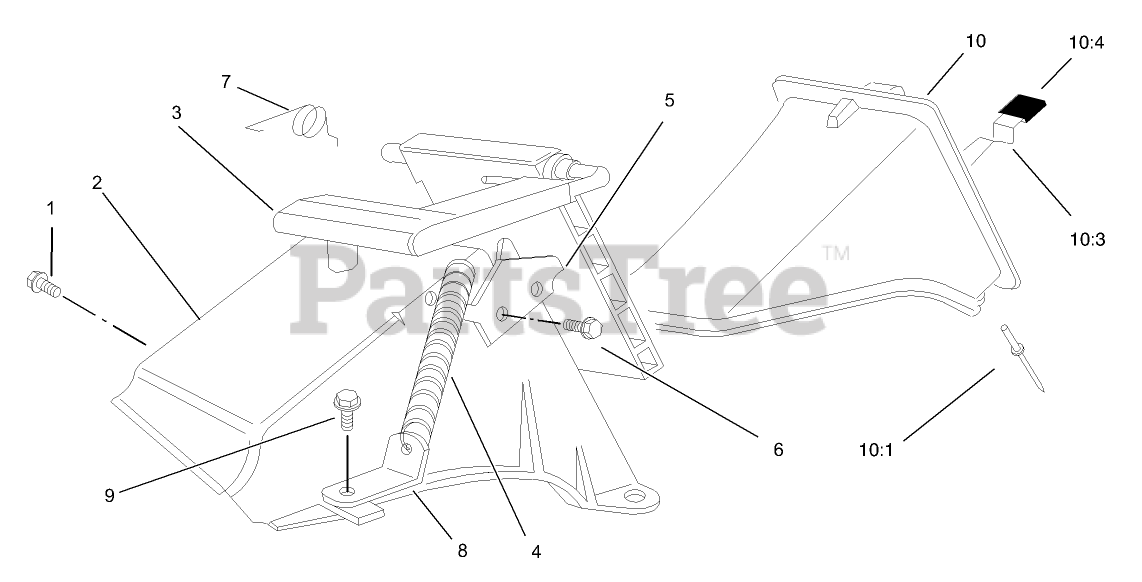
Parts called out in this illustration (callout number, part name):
1	SCREW AND WASHER ASM
2	TUNNEL-DISCHARGE
3	DISCHARGE DOOR ASM
4	SPRING-DOOR
5	PLATE-LATCH
6	SCREW-PLASTITE
7	RETAINER-DOOR
8	BRACKET-SPRING
9	SCREW-HWH
10	DISCHARGE PLUG ASM
10:1	RIVET-HEAD, FLAT
10:3	LATCH-PLUG, DISCHARGE
10:4	GRIP-LATCH
